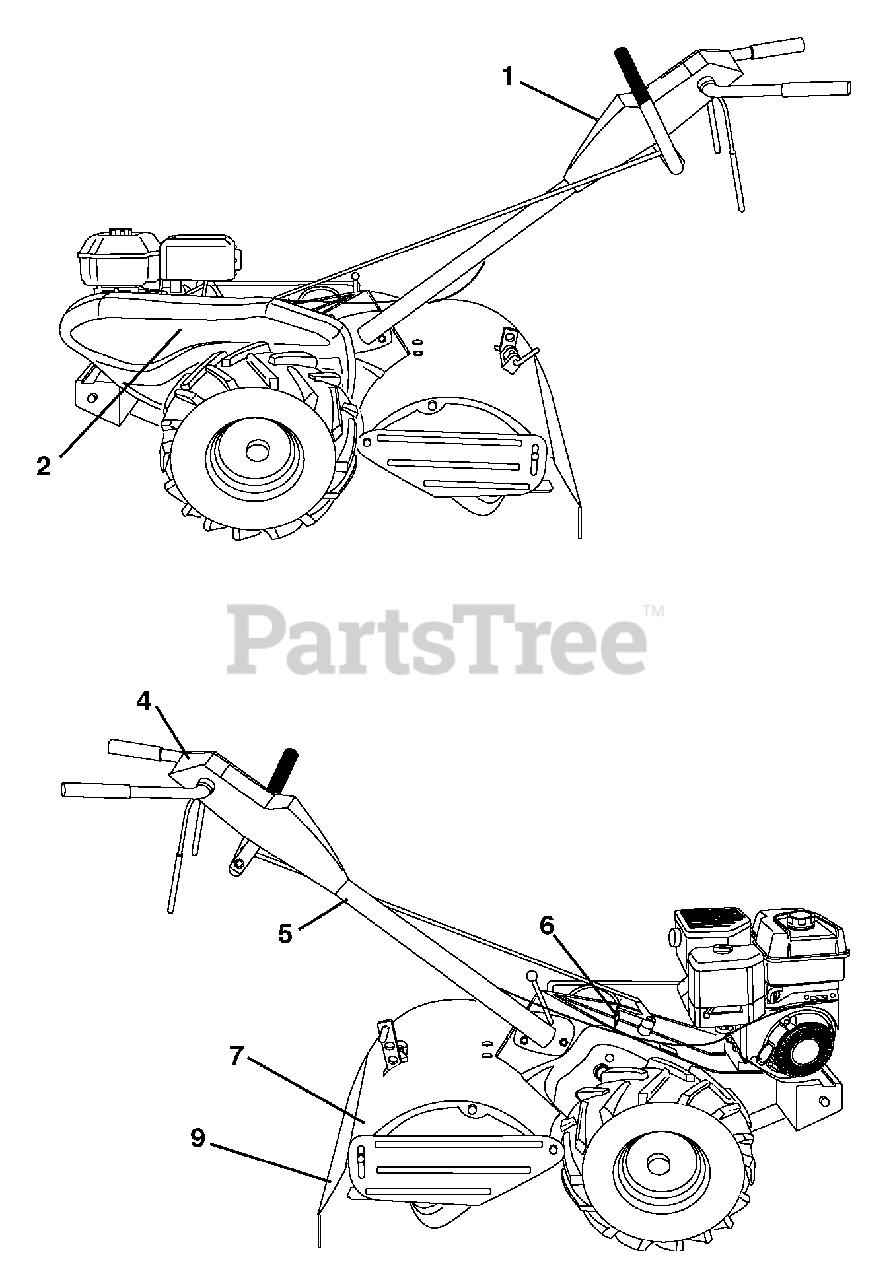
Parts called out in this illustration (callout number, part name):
1	Decal, CNTRL PNL
2	Decal, Decal, Blt Grd
4	Decal, Instruction, Tilling
5	Decal, Hand Placement
6	Decal, Shift Indicator
7	Decal, caution
9	Decal, Warning, Rotating Tines
